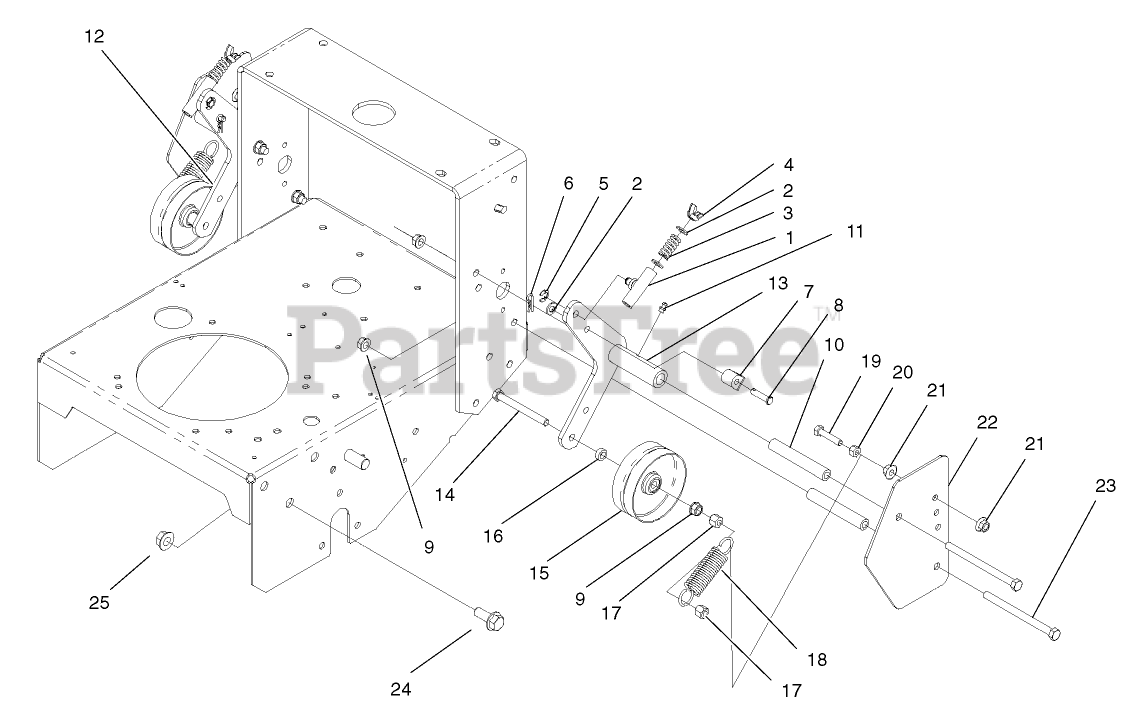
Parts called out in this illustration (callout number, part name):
1	SWIVEL-BRAKE
2	WASHER-PLAIN
3	SPRING-COMPRESSION
4	NUT-WING, LOCK
5	RING-RETAINING
6	PIN-COTTER
7	FITTING-ROD
8	PIN-CLEVIS
9	NUT-FLANGE
10	SPACER-SHIELD
11	FITTING-GREASE
12	ARM-IDLER ASM, RH
13	ARM-IDLER ASM, LH
14	Screw-HH
15	IDLER-WHEEL, DRIVE
16	Spacer-Pulley
17	NUT-LOCK, NI
18	SPRING-EXTENSION
19	SCREW-HH
20	NUT-LOCK, NI
21	NUT-HF
22	SHIELD,WHEEL DRIVE
23	SCREW-HH
24	SCREW-HHF
25	NUT-HF
